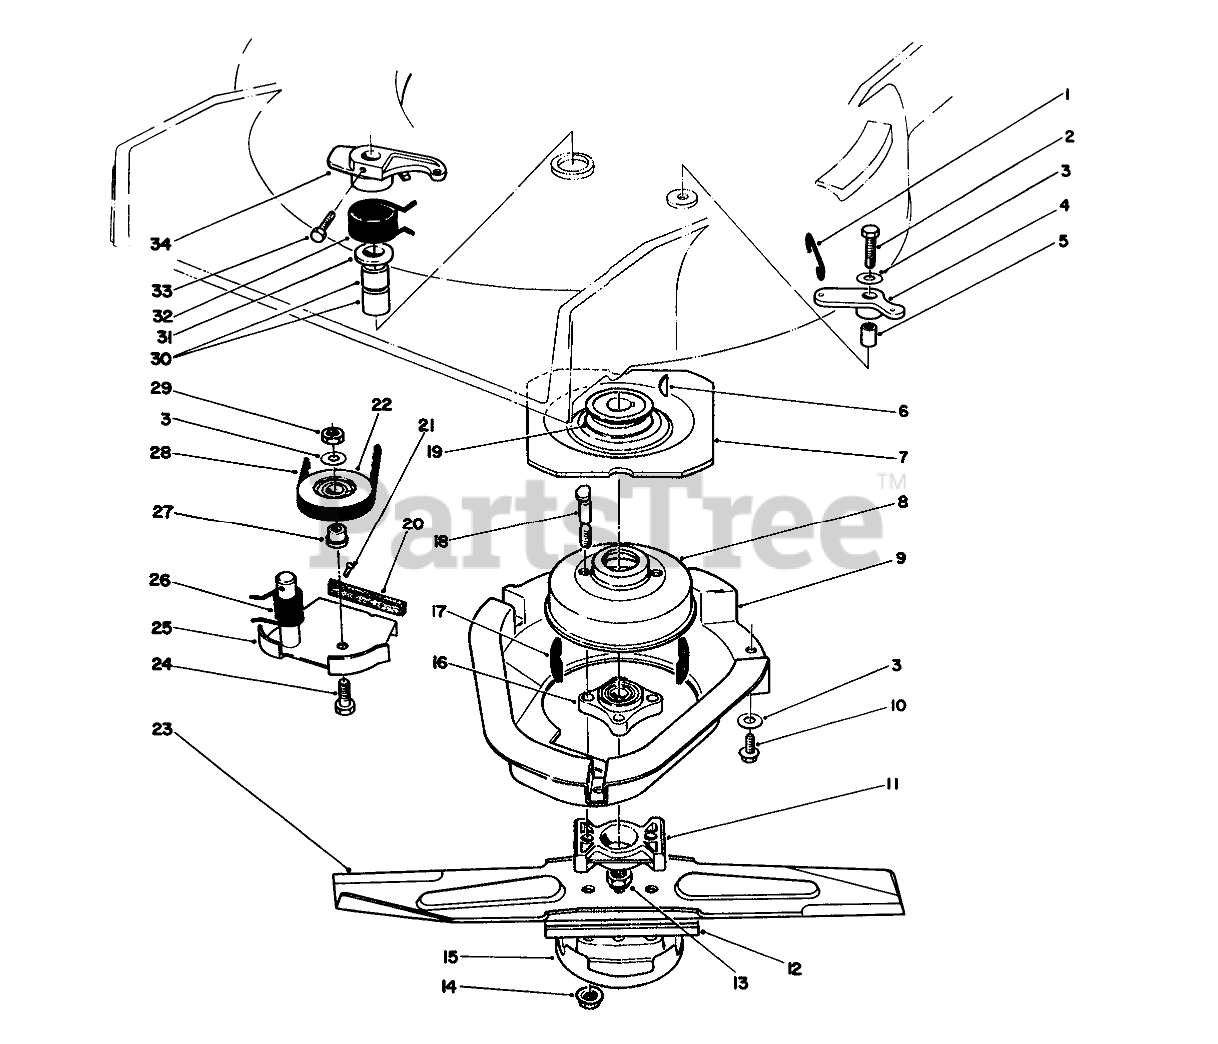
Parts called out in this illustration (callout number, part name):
1	LINK-CONTROL
2	SCREW-HH
3	WASHER-PLAIN
4	BELLCRANK
5	SLEEVE-BELLCRANK
6	KEY-WOODRUFF
7	Flywheel
8	Drum-Brake
9	SHIELD BBC
10	SCREW-HWHTF
11	SPACER-BLADE
12	Stiffener
13	NUT-LOCK, NI
14	NUT-LOCK
15	CUP-SCALP, ANTI
16	HUB ASM
17	DAMPENER-VIBRATION
18	BOLT-BLADE
19	PULLEY
20	Pad-Brake
21	.185 DIA X .375 RT +
22	PULLEY-IDLER
23	Blade
24	SCREW-HH
25	Brake Plate (Incl. Ref. #20 & 21)
26	SPRING-TORSION
27	HUB-PULLEY, IDLER
28	V-BELT
29	NUT-LOCK, NI
30	BEARING
31	WASHER
32	SPRING-TORSION
33	SCREW-HH
34	LEVER
